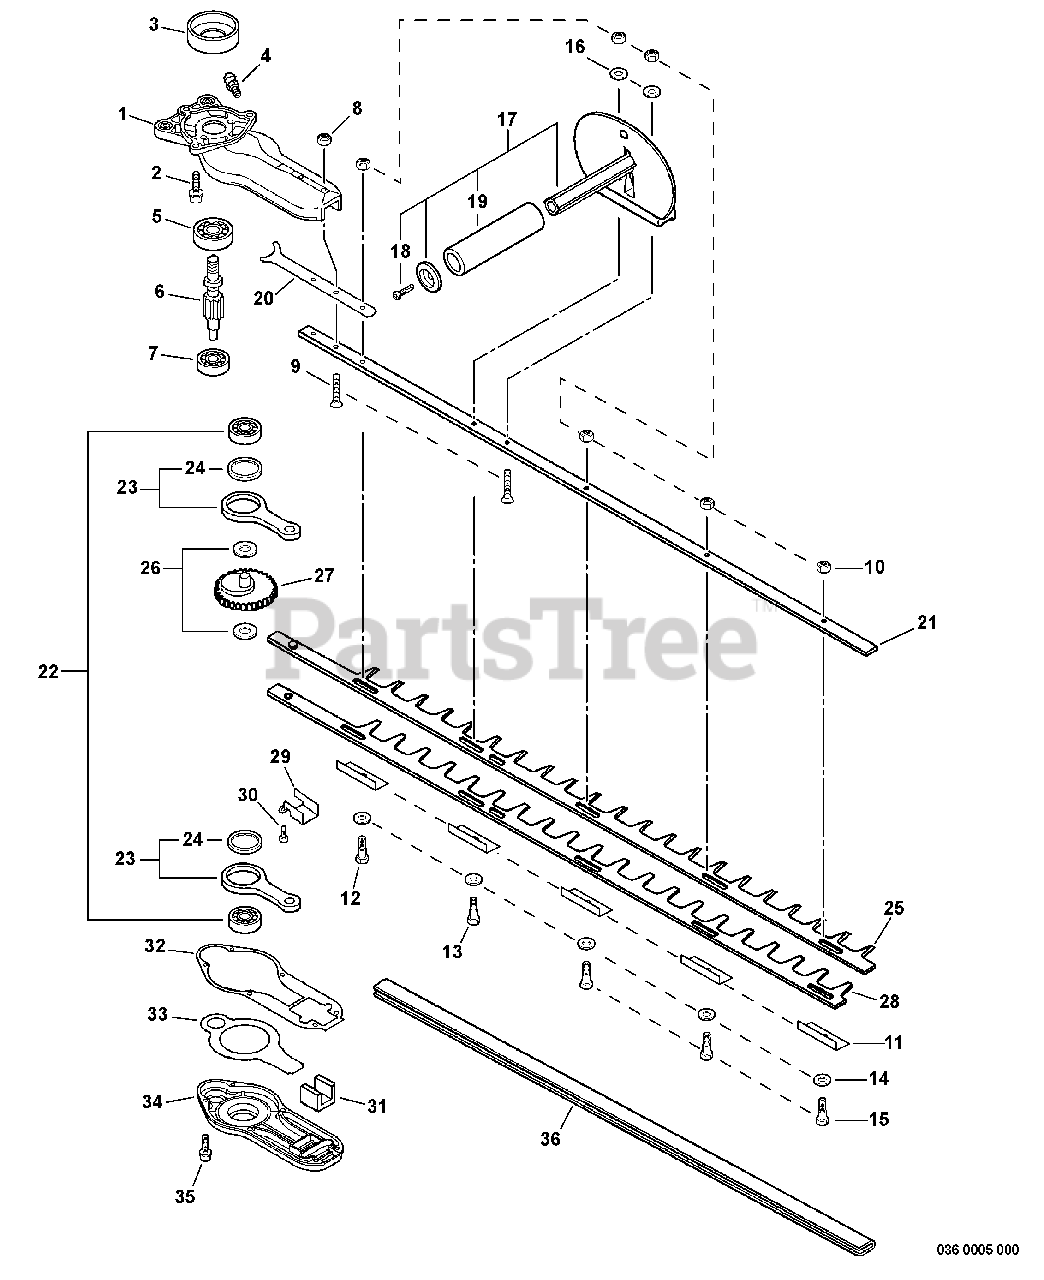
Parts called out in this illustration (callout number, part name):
1	CASE, GEAR - UPPER
2	BOLT 6×18
3	DRUM, CLUTCH
4	FITTING, GREASE
5	BEARING, BALL 6200
6	GEAR, SPUR
7	BEARING, BALL 608ZZ
8	NUT, FLANGE M6
9	BOLT 6×30
11	GUIDE, BLADE
12	BOLT 6×25
13	BOLT 6×40
15	BOLT 6×22
16	WASHER 6.5×13×1
17	FRONT HANDLE ASSY
18	SCREW 5×14
19	GRIP, HANDLE
20	PLATE, EYE
21	SUPPORT, BLADE 30"
22	BEARING, BALL 6200
23	ROD, CONNECTING
24	BEARING, NEEDLE 30
25	BLADE, UPPER 30"
26	WASHER, THRUST 10
27	GEAR, SPUR
28	CUTTER, 30" LOWER
29	GUIDE, BLADE
30	BOLT 4×16
32	GASKET, GEAR CASE
33	PLATE, GEAR CASE
34	COVER, GEAR CASE
35	BOLT 4×16
36	SCABBARD
